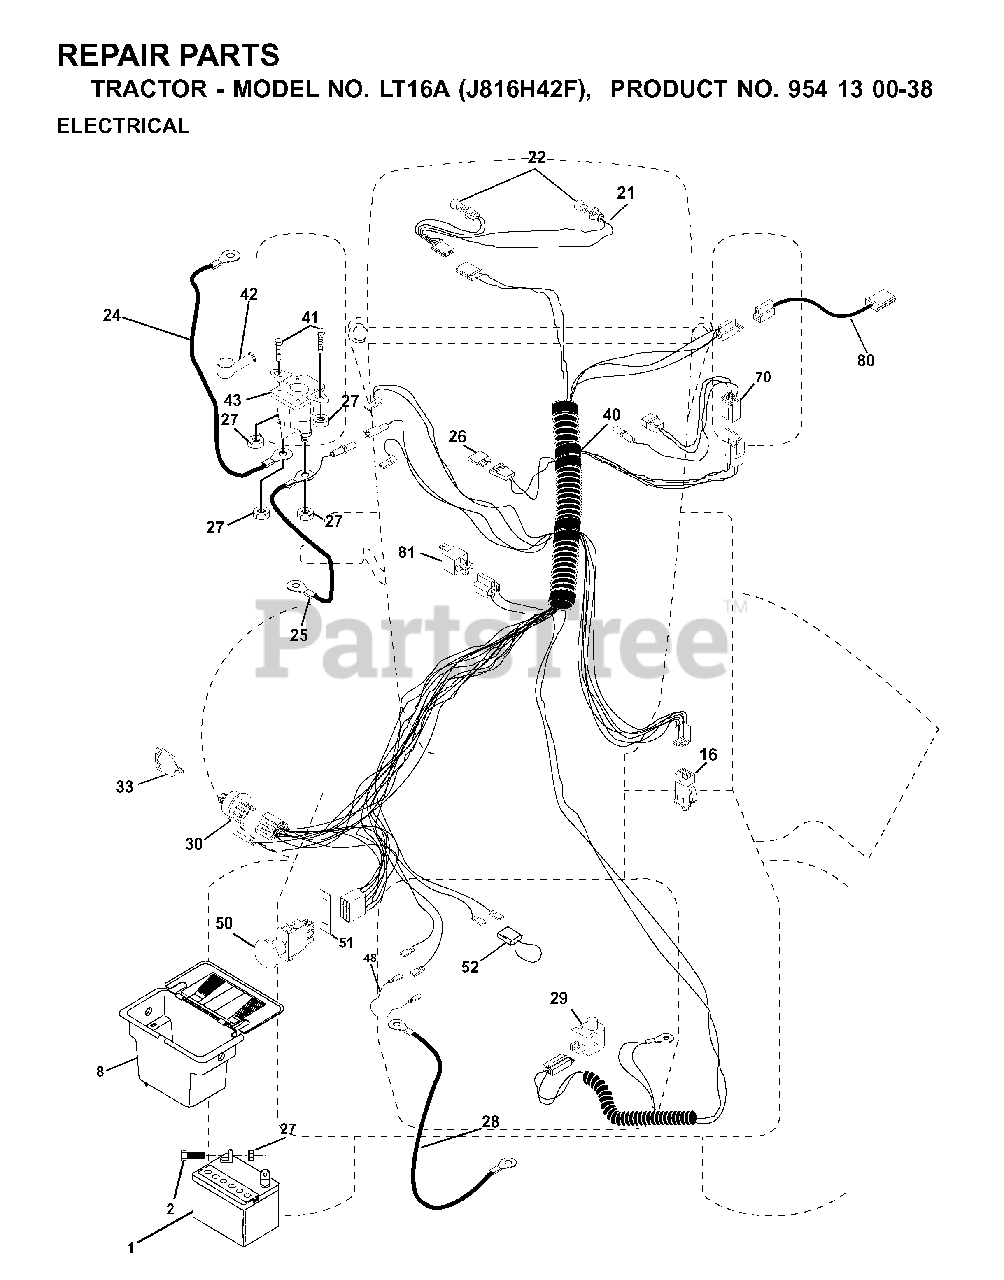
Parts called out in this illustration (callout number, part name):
1	BATTERY 12 VOLT 25 AMP
8	CASE BATTERY MECH HINGE
16	SWITCH INTERLOCK
20	NUT
21	HARNESS ASM, LIGHT W/4152J
22	LIGHTBULB
24	BATTERY CABLE GT
25	CABLE BATTERY
26	FUSE 15 AMP
27	NUT
28	CABLE T
29	PLUNGER SWITCH (COLOR:OLIVE)
33	KEY MLD GEN DELTA
40	HARNESS, ELEC IGNITION
42	TERMINAL COVER
43	SOLINOID
50	PTO SWITCH
51	RETAINING RING
52	WIRE PROTECTION LOOP
80	HARNESS, CLUTCH
81	RELAY.ASSY.T
